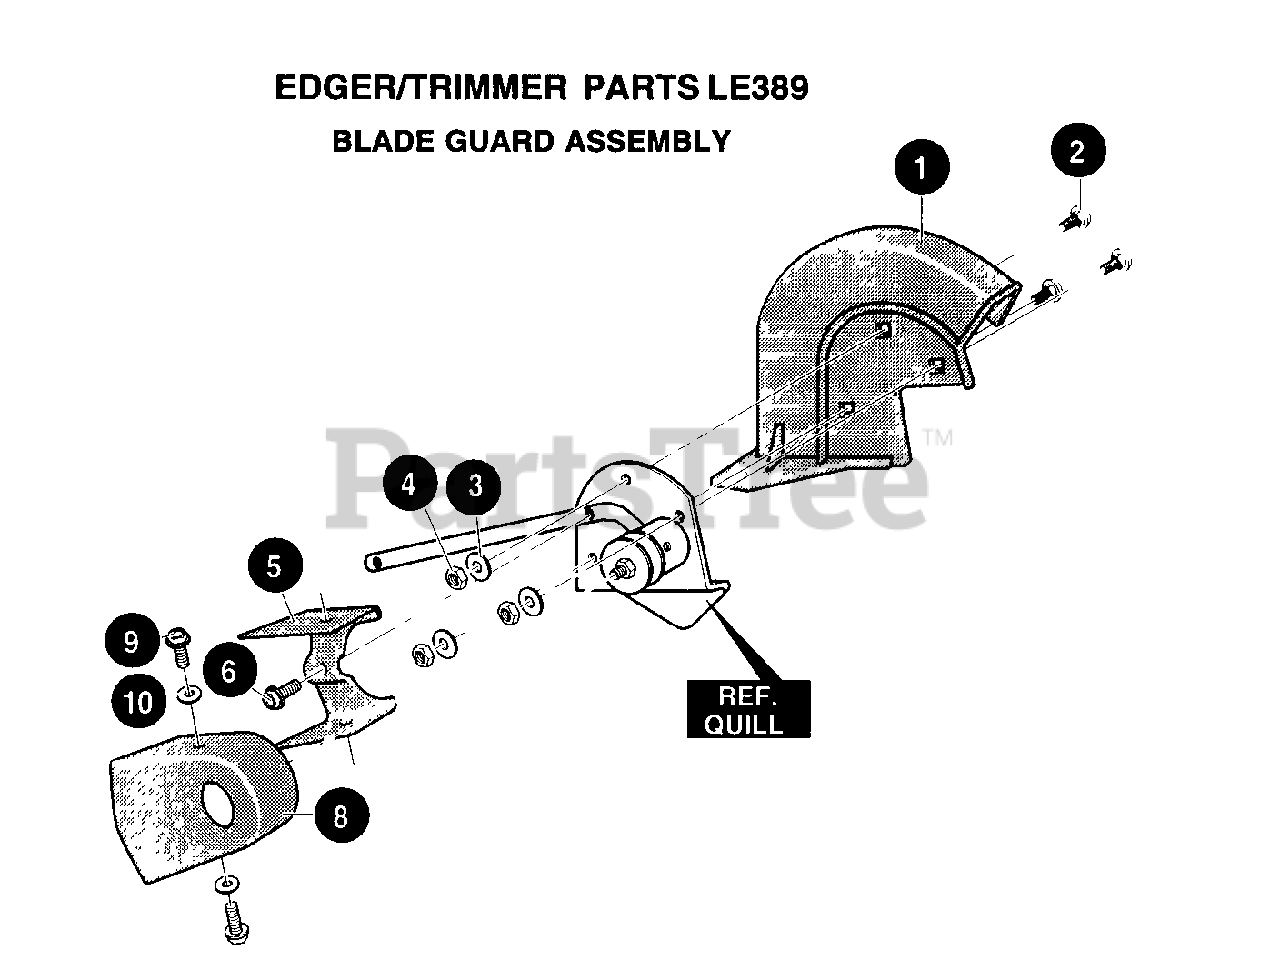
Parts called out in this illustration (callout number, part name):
1	Blade Guard
2	Carr. Bolt 5/16-18 x .63
3	Flatwasher .344 x .69 x .065
4	Nut, 5/16-18 Reghexctrlk
5	Guide, Belt Front
6	Screw, 1/4-20 x .50 Tap
8	Cover, Quill Pulley
9	Screw, 10-24 x .50 Tap
10	Flatwasher .203 x 56 x .040
